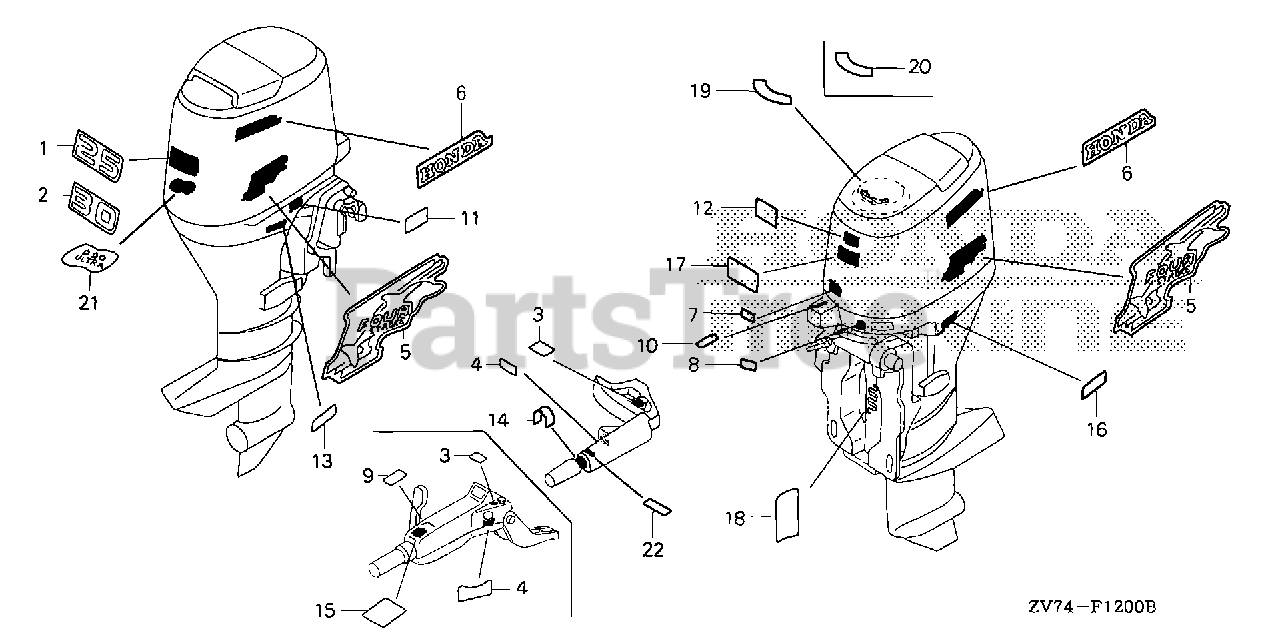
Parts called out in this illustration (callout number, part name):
1	MARK, RR. (25)
5	MARK, SIDE
6	MARK, SIDE STRIPE
7	MARK (E-SPEC)
13	LABEL, OIL CAUTION (ENGLISH)
16	LABEL, STORING CAUTION (ENGLISH)
17	LABEL, WARNING OPERATOR (ENGLISH)
18	LABEL, ASSIST TILT CAUTION (ENGLISH)
19	MARK, EMERGENCY START (ENGLISH)
